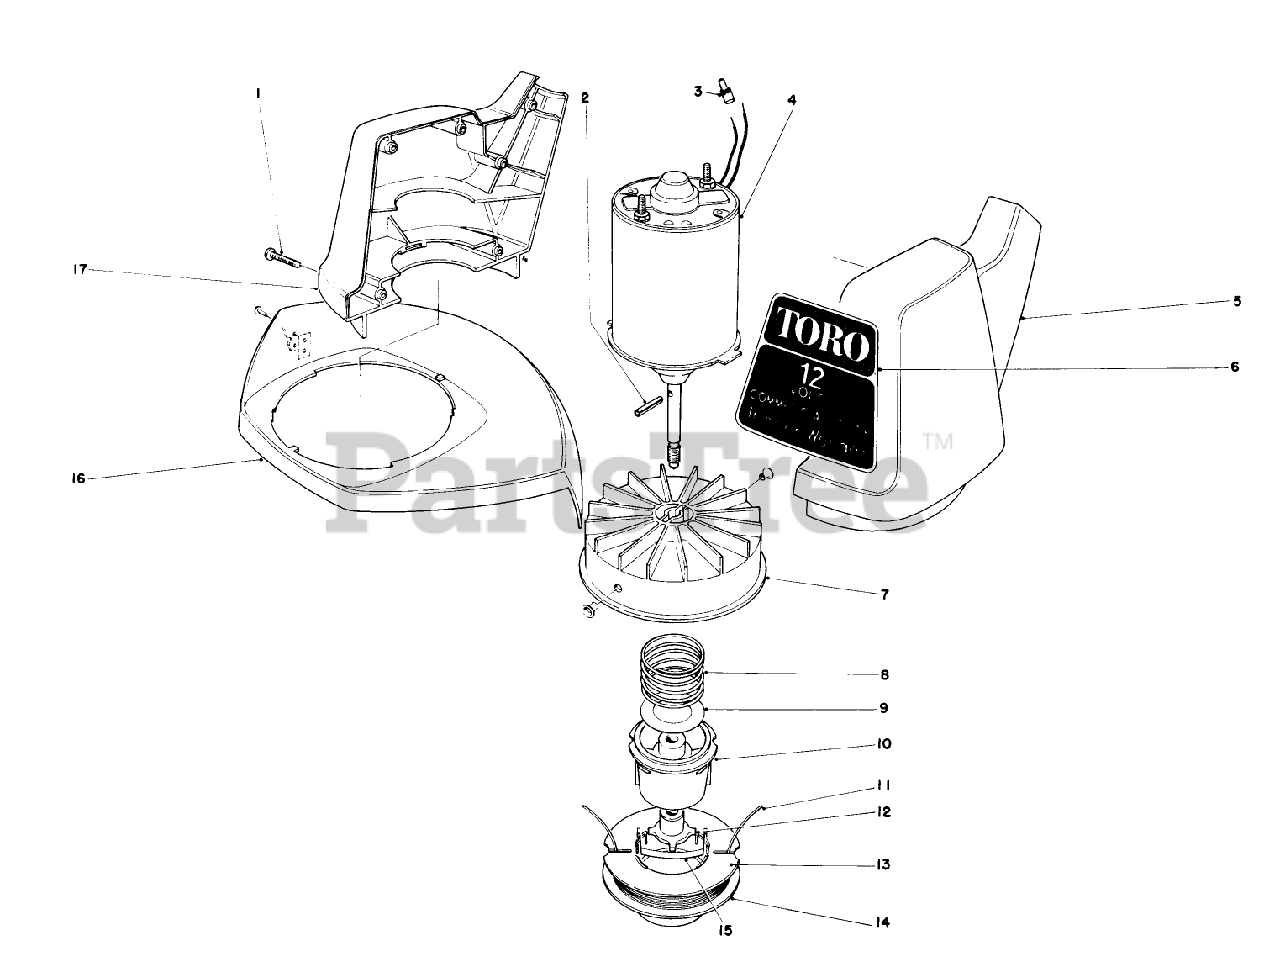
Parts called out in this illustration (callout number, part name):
1	SCREW-PPH
2	COIL PIN
3	Connector
4	Motor D.C.
5	Housing-L.H.
6	Decal-Commercial Duty
7	Drum W/Eyelets
8	SPRING COMPRESSION
9	WASHER-FLAT
10	SPOOL CORE
11	50-, .065" Dia. Line In Coil
12	Driver
13	Empty SPooI
14	50-,.065" Dia. Line Prewound On Spool
15	SADDLE-SPOOL CAP
16	Shield with Cut Off Blade
17	Housing-R.H.
